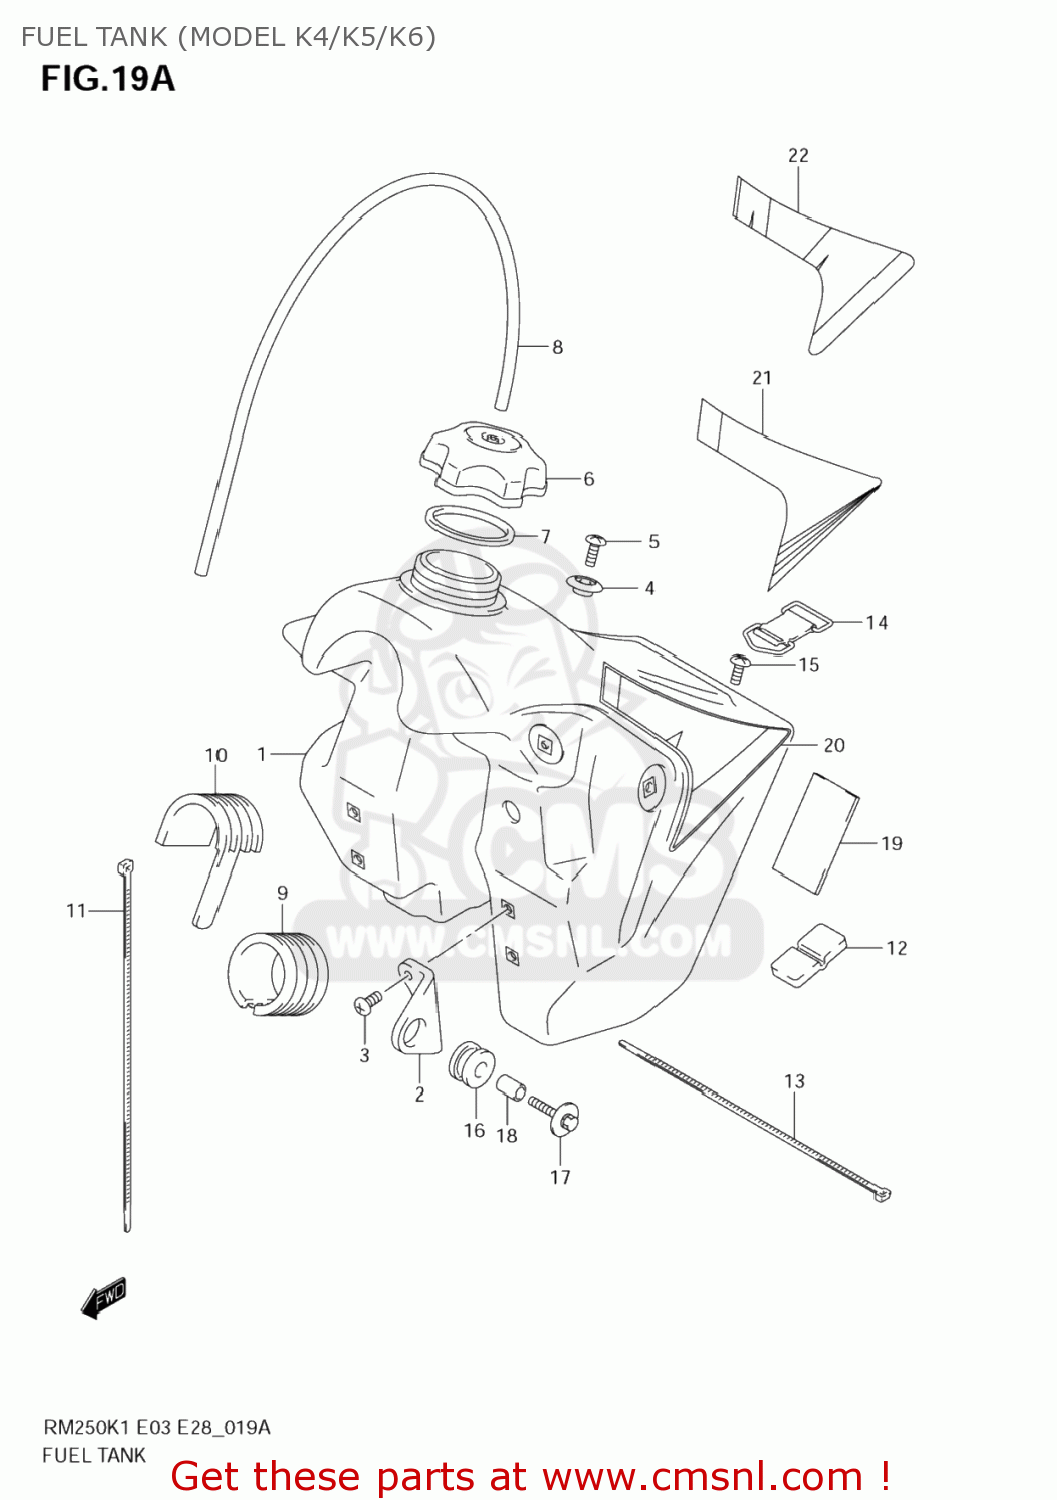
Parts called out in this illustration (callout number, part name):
1	TANK COMP,FUEL
2	BRACKET,FUEL TANK FR
3	SCREW 6X12
4	HOOK,SEAT FR
5	SCREW
6	CAP,FUEL TANK FILLER
7	GASKET,CAP (NAS)
8	HOSE(5X8.2X600)
9	CUSHION,FUEL TANK NO.1
10	CUSHION,FUEL TANK
11	CLAMP(L:300)
12	CUSHION
13	CLAMP(L:250)
14	BAND,FUEL TANK RR
15	SCREW(6X13.5)
16	CUSHION,MUFFLER
17	BOLT(6X35)
18	SPACER(6.5X9X13.5)
19	PROTECTOR(40X85X5)
20	TAPE SET,FUEL TANK
21	TAPE SET,FUEL TANK
22	TAPE SET,FUEL TANK
